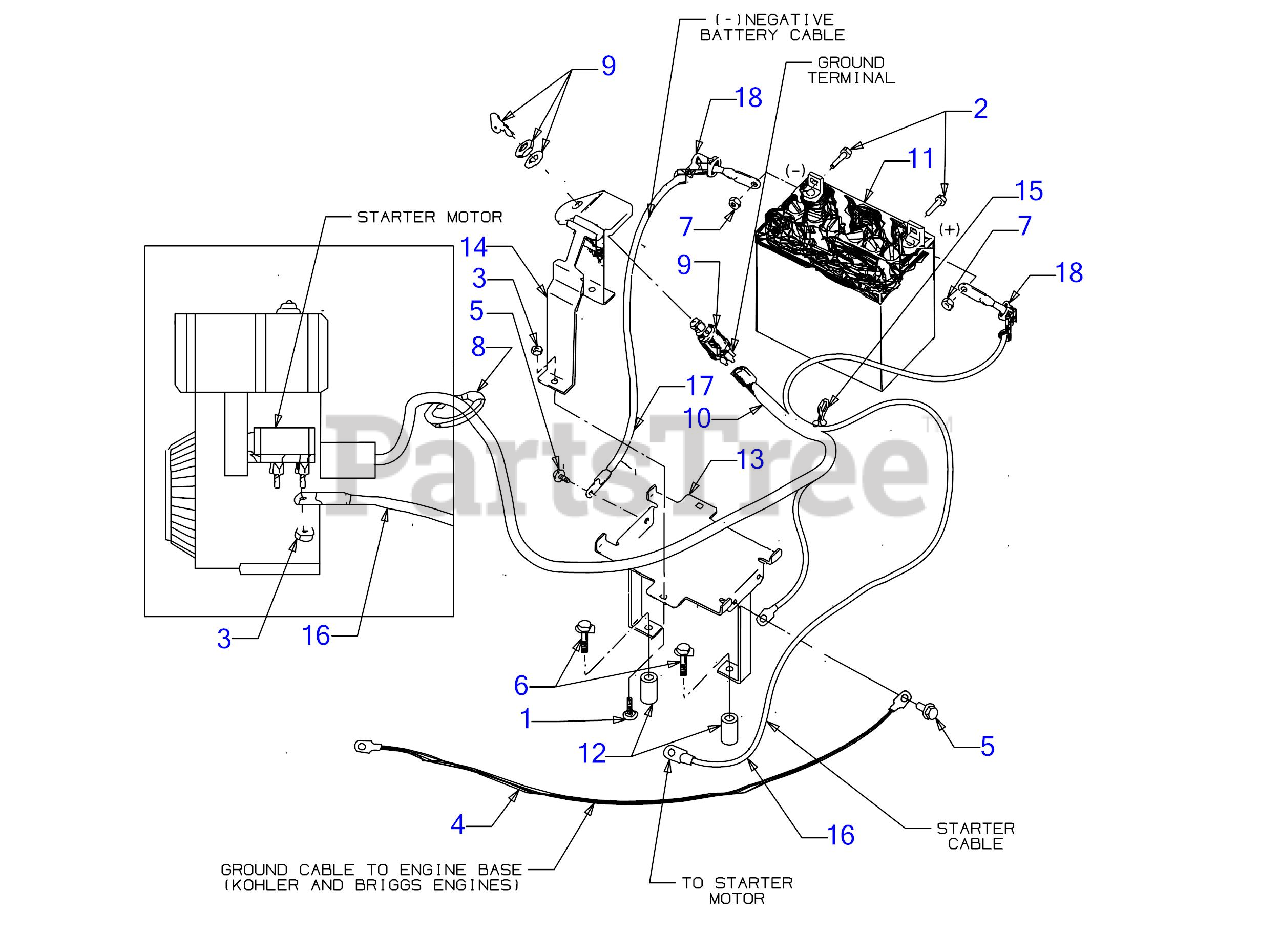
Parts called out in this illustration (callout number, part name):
1	CARRIAGE BOLT
2	SCREW-FLANGE
3	NUT-FLANGE
4	CABLE-BATTERY
5	SCREW 1/4-20 X.500
6	SCREW 3/8-16 x 2.75 GR5
8	7" CABLE TIE
9	IGNITION SWITCH
10	MAIN HARNESS
11	Purchase Battery Locally
13	OPC BATTERY BRACK
14	KEYSWITCH WITH DE
15	TIE-TWIST LOCK
16	CABLE-BATTERY
17	CABLE-BATTERY 10IN
18	BOOT-BATTERY CABLE
